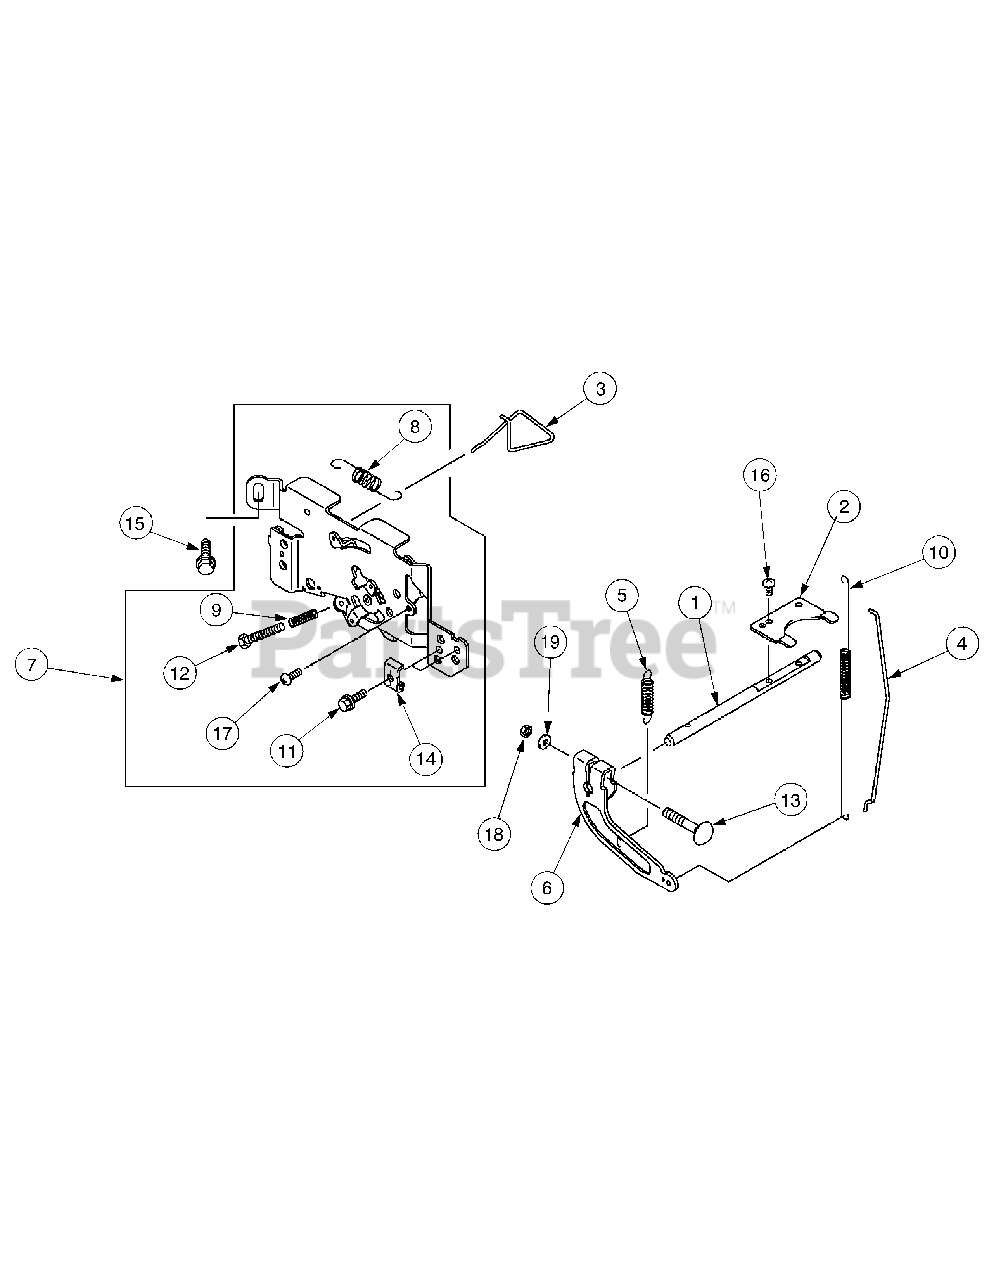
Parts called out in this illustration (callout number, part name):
1	Shaft
2	Plate
3	Link, Choke
4	Link
5	Spring, Governor
6	Arm, Governor
7	Panel, Control
8	Spring
13	Bolt, 6 x 35
15	Bolt, Flanged
16	Screw, Pan Hd.
17	Screw, Pan Hd.
18	Nut, Hex
19	Washer, Plain
